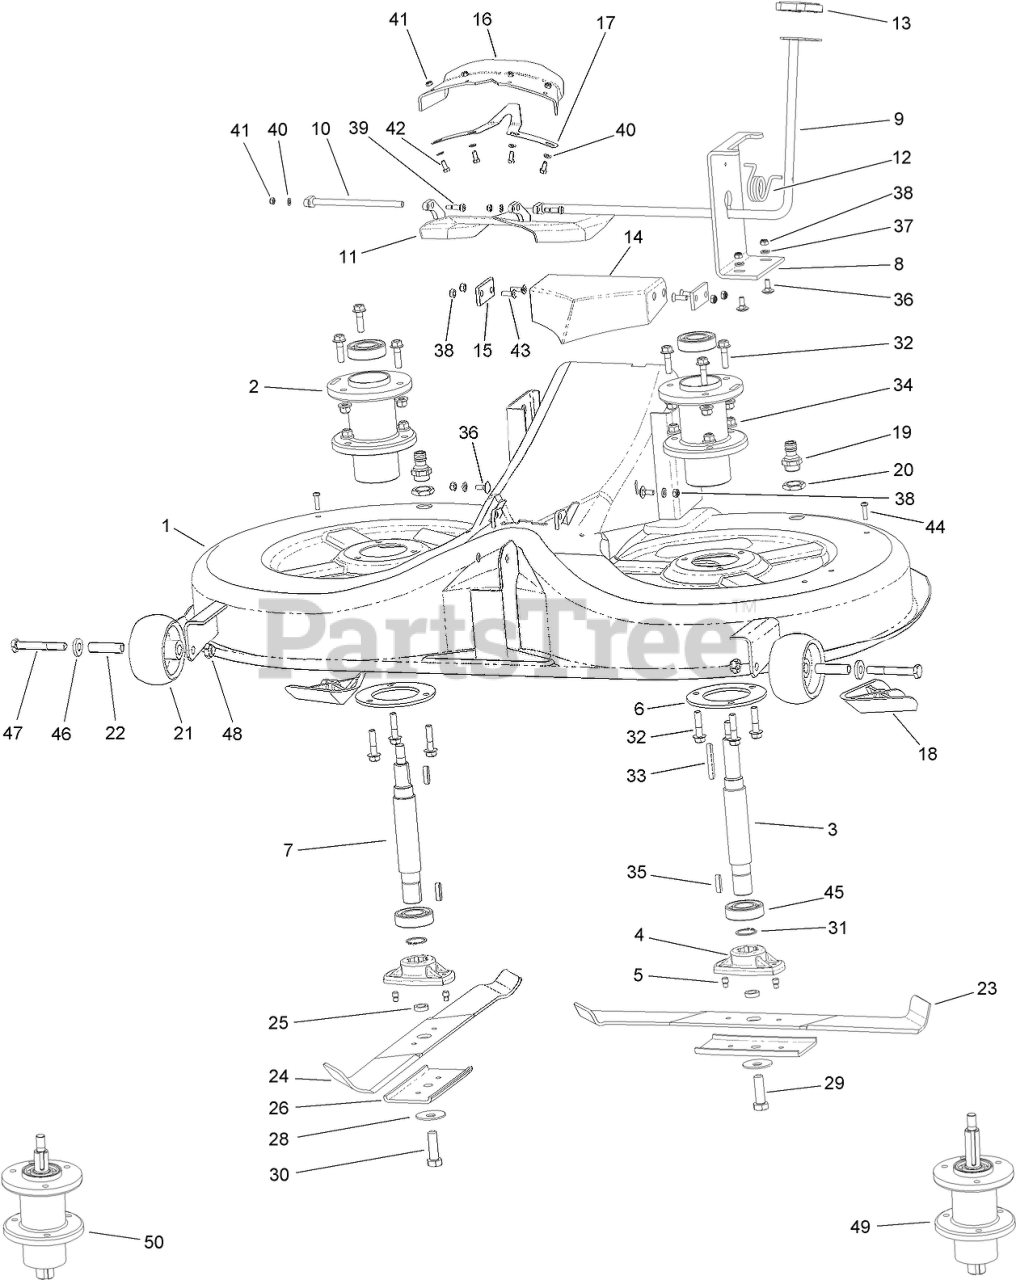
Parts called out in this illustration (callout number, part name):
1	DECK ASM WITH DECALS
2	HOUSING-SPINDLE
3	SHAFT-BLADE, LEFT
4	Adapter-Blade
5	PIN-SHEAR, GROOVED
6	SUPPORT-RING
7	Shaft-BLADE, Right
8	HOLDER
9	LEVER-FOOT
10	Rod-Door, Mulch
11	DOOR-MULCH
12	SPRING
13	PAD-PEDAL
14	Baffle-Center
15	PLATE-BAFFLE, CENTER
16	Gasket-Door, Mulch
18	Kicker
19	CONNECTION
21	WHEEL-GAUGE
22	SPACER
23	BLADE-LH
24	BLADE-RH
25	Spacer
26	STIFFENER-BLADE
28	WASHER-BLADE
29	BOLT-HH
30	BOLT-BLADE, HH
31	RING-LOCKING
32	BOLT-HHF
34	NUT-LOCK, HHF
35	KEY-SQUARE
36	SCREW-CARR
37	WASHER
38	NUT-LOCK
40	WASHER
41	NUT-LOCK
44	SCREW-TAP, PPH
45	BEARING-BALL
46	WASHER-FLAT
47	SCREW-HH
48	NUT-LOCK
49	LH SPINDLE HOUSING ASM
50	RH SPINDLE HOUSING ASM
